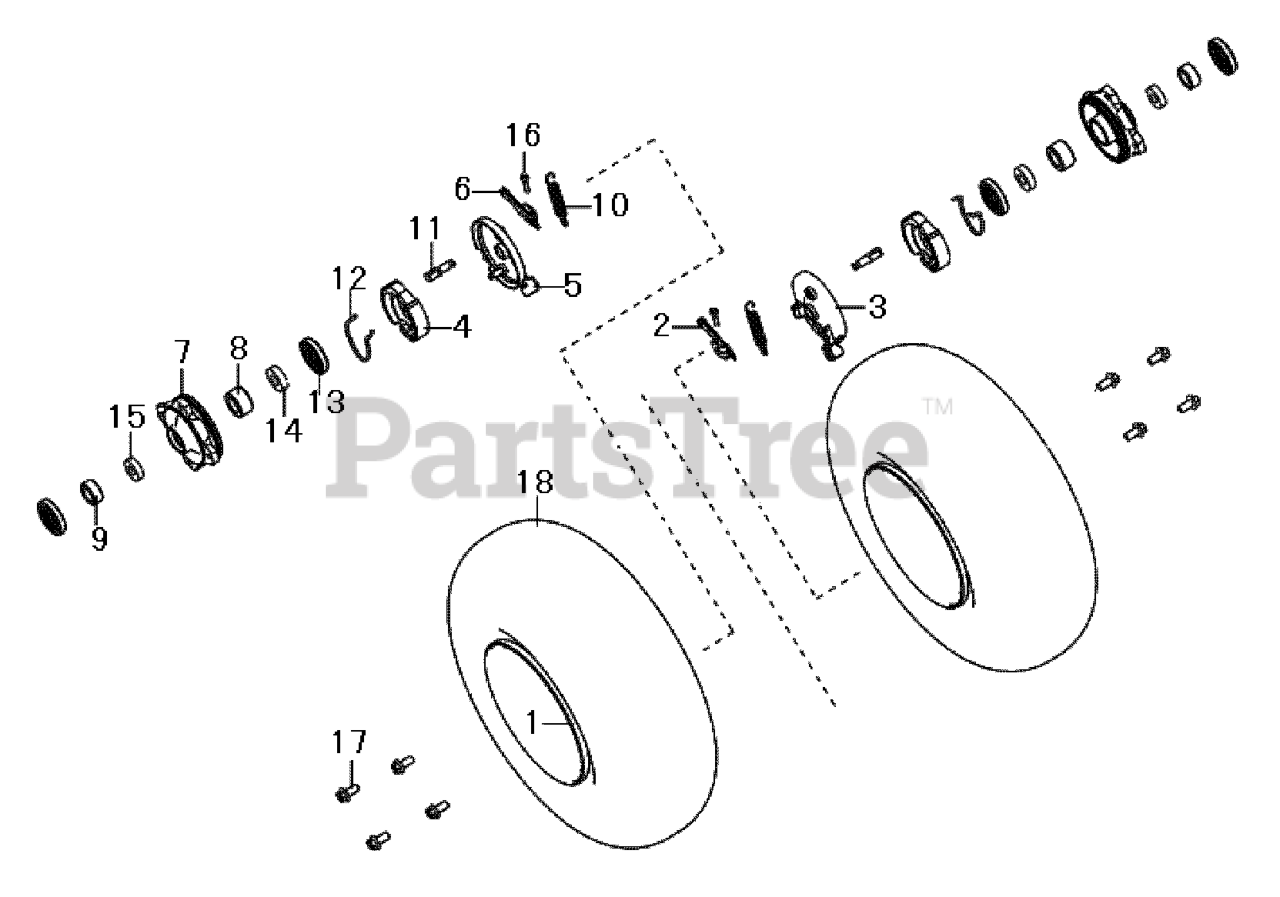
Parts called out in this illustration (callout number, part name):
1	RIM ASSY., FRONT 100cc
2	ARM, BRAKE (RIGHT SIDE)
3	PLATE, BACKING (RIGHT)
4	BRAKE SHOE
5	PLATE, BACKING (LEFT)
6	ARM, BRAKE (LEFT SIDE)
8	SPACER, INNER
9	SPACER, OUTER
10	RETURN SPRING
11	CAMSHAFT
14	BEARING, INNER
15	BEARING
